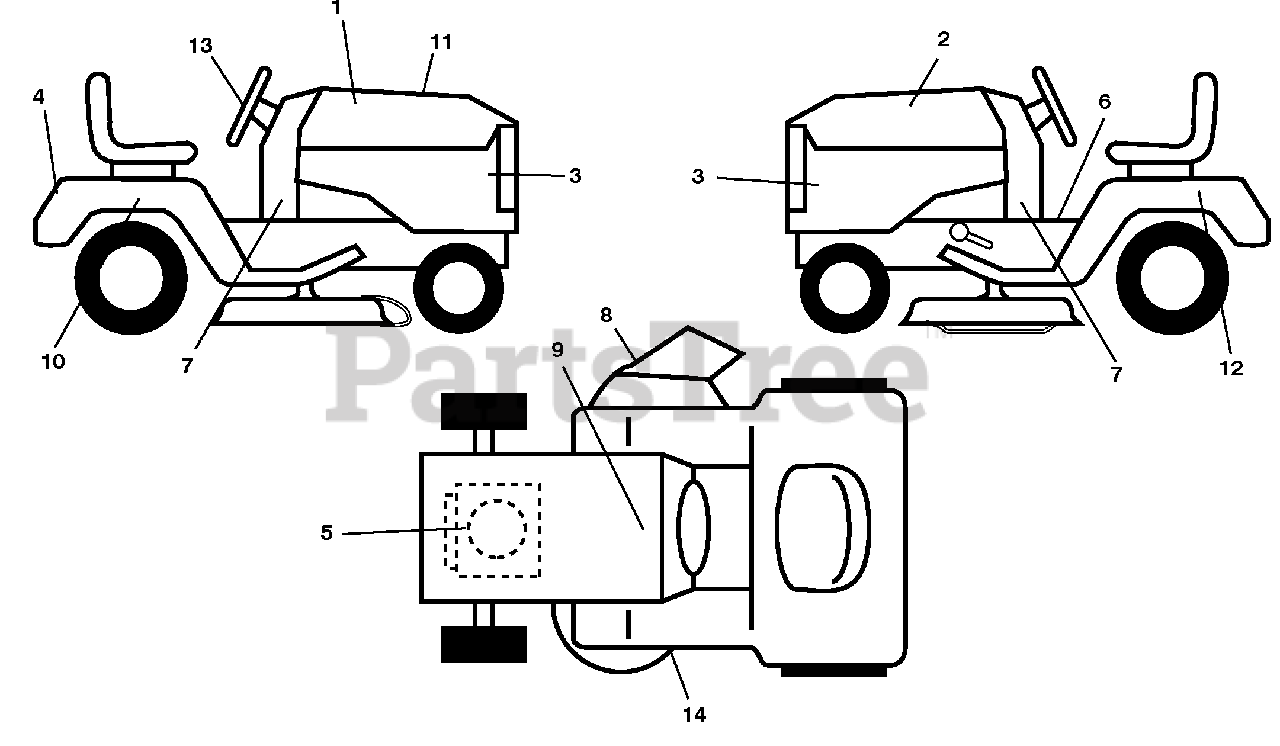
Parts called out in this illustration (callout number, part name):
1	Decal, Hood RH
2	Decal, Hood LH
3	Decal, Side Panel
4	Decal, Fender
5	Decal, Engine
6	Decal, Fender
7	Decal, Lower Dash
8	Decal, Warning
9	Decal, Battery Dnge/Poi
10	Decal, Fender Side RH
11	Decal, Replacement
12	Decal, Fender Side LH
13	Decal, Steering Wheel
14	Decal, Mower Schematic
14	Pad, Footrest, RH
14	Decal, Bypass
14	Pad, Footrest, LH
14	Manual, Operator's (Eng/French)
14	Manual, Parts
